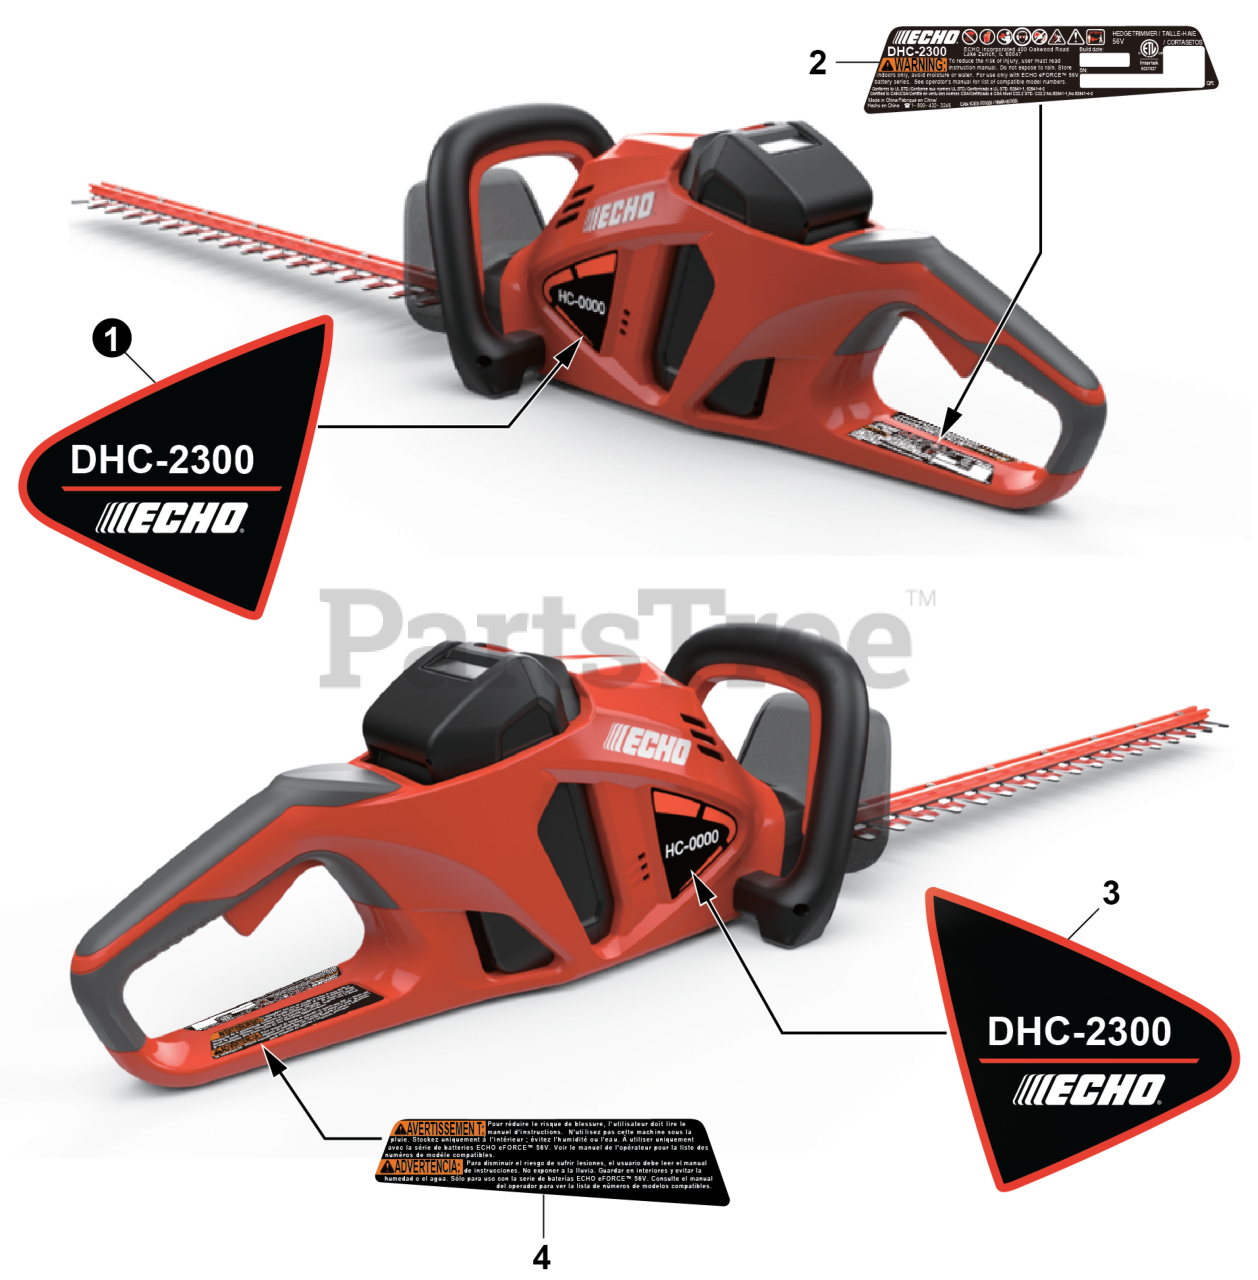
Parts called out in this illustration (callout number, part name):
1	BRAND LOGO,LEFT HOUSING
2	LABEL,LEFT HANDLE
3	LABEL,RIGHT HANDLE
4	BRAND LOGO,RIGHT HOUSING
